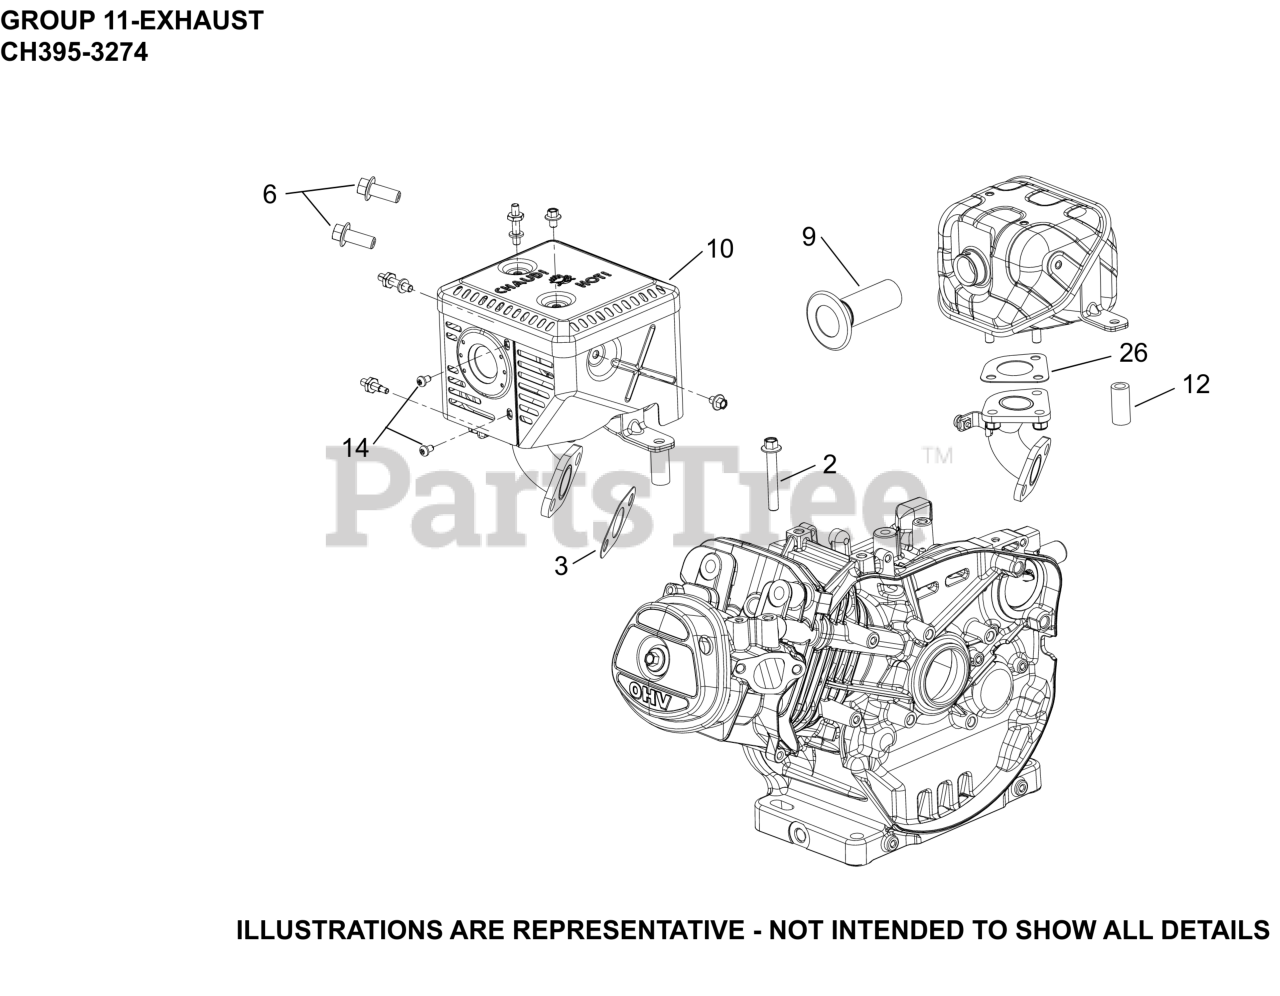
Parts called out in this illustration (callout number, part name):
2	SCREW, M8 X 55
3	GASKET, MUFFLER
6	SCREW, M10 X 25
9	ARRESTOR ASSEMBLY, SPARK
10	MUFFLER ASSEMBLY W/HEAT SHIELD
12	POST, MUFFLER BRACKET
14	SCREW, M5 X 8
26	GASKET, MUFFLER
